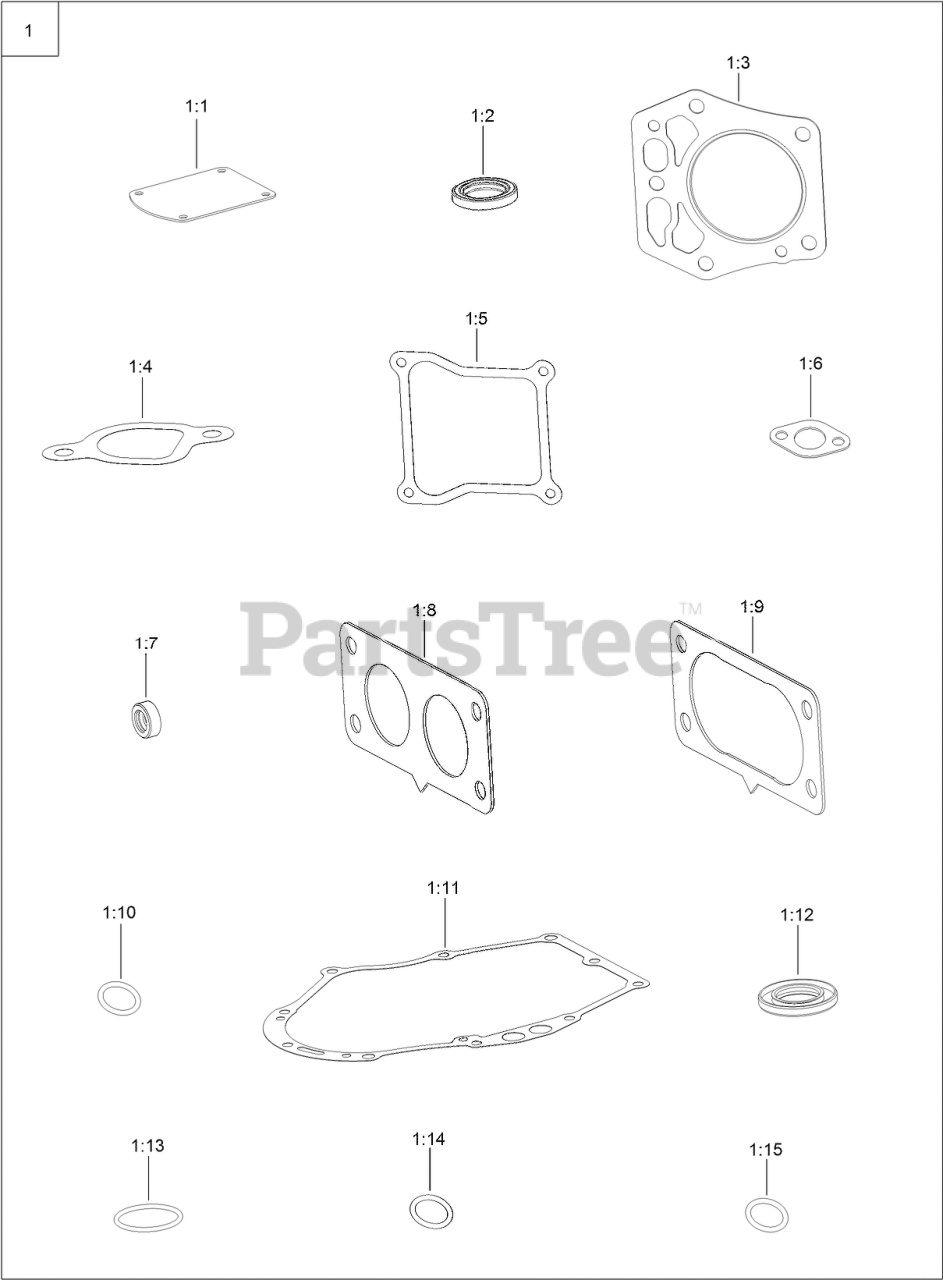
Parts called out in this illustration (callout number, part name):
1	GASKET AND SEAL KIT
1:1	GASKET-BREATHER
1:2	SEAL-OIL
1:3	GASKET-HEAD, CYLINDER
1:4	GASKET-INTAKE
1:5	GASKET-VALVE COVER
1:6	GASKET-EXHAUST
1:7	SEAL-OIL
1:8	GASKET-CARBURETOR
1:9	GASKET-CARBURETOR
1:10	O-RING
1:11	GASKET-COVER, CRANKCASE
1:13	O-RING
1:14	O-RING
1:15	O-RING
